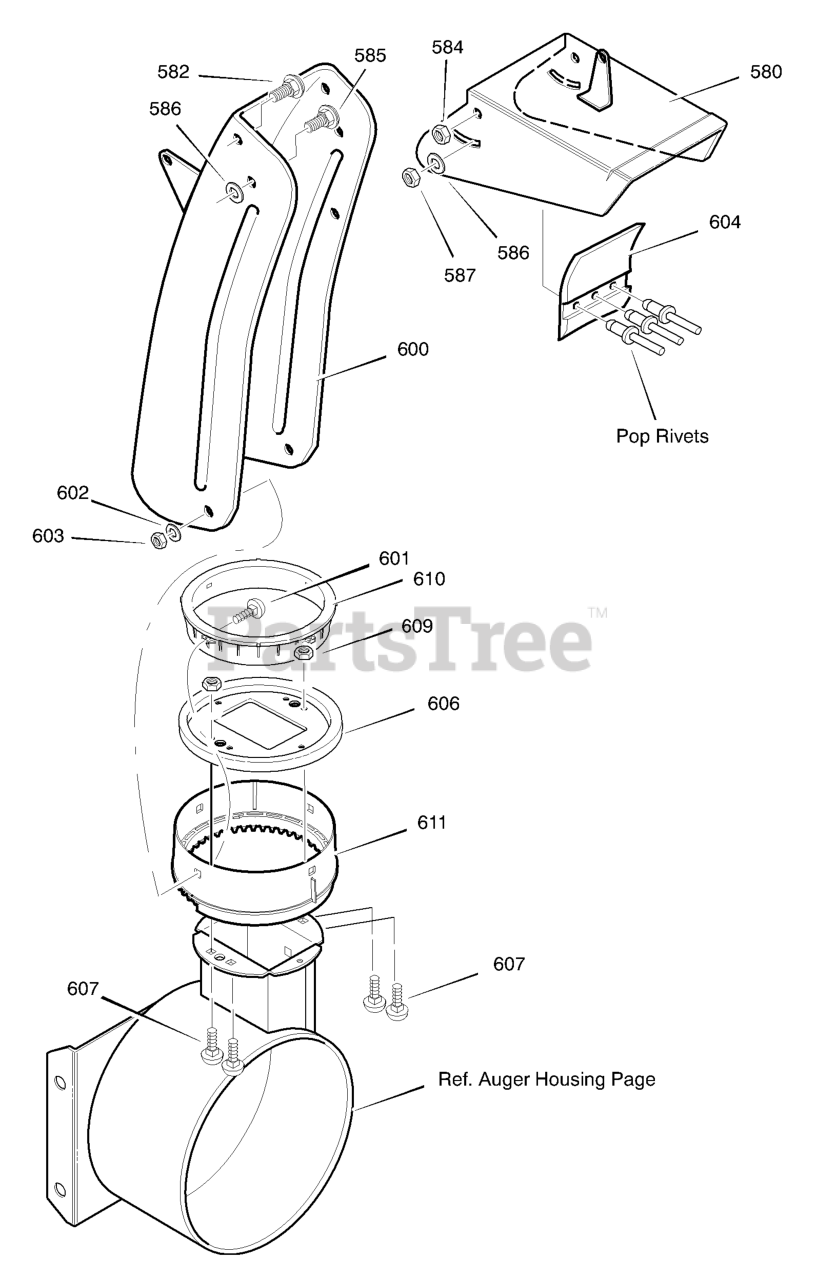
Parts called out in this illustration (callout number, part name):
580	CHUTE, UPPER W/REMOTE
582	SCREW, 5/16-18 x 0.75
584	NUT
585	SCREW, 5/16-18 x 0.75
586	PLASTIC WASHER
587	NUT
600	CHUTE, LOWER W/REMOTE
602	WASHER, FLAT
603	NUT
606	CHUTE COLLAR
607	BOLT
609	NUT
610	RETAINER, RING INNER
611	RETAINER, RING OUTER
